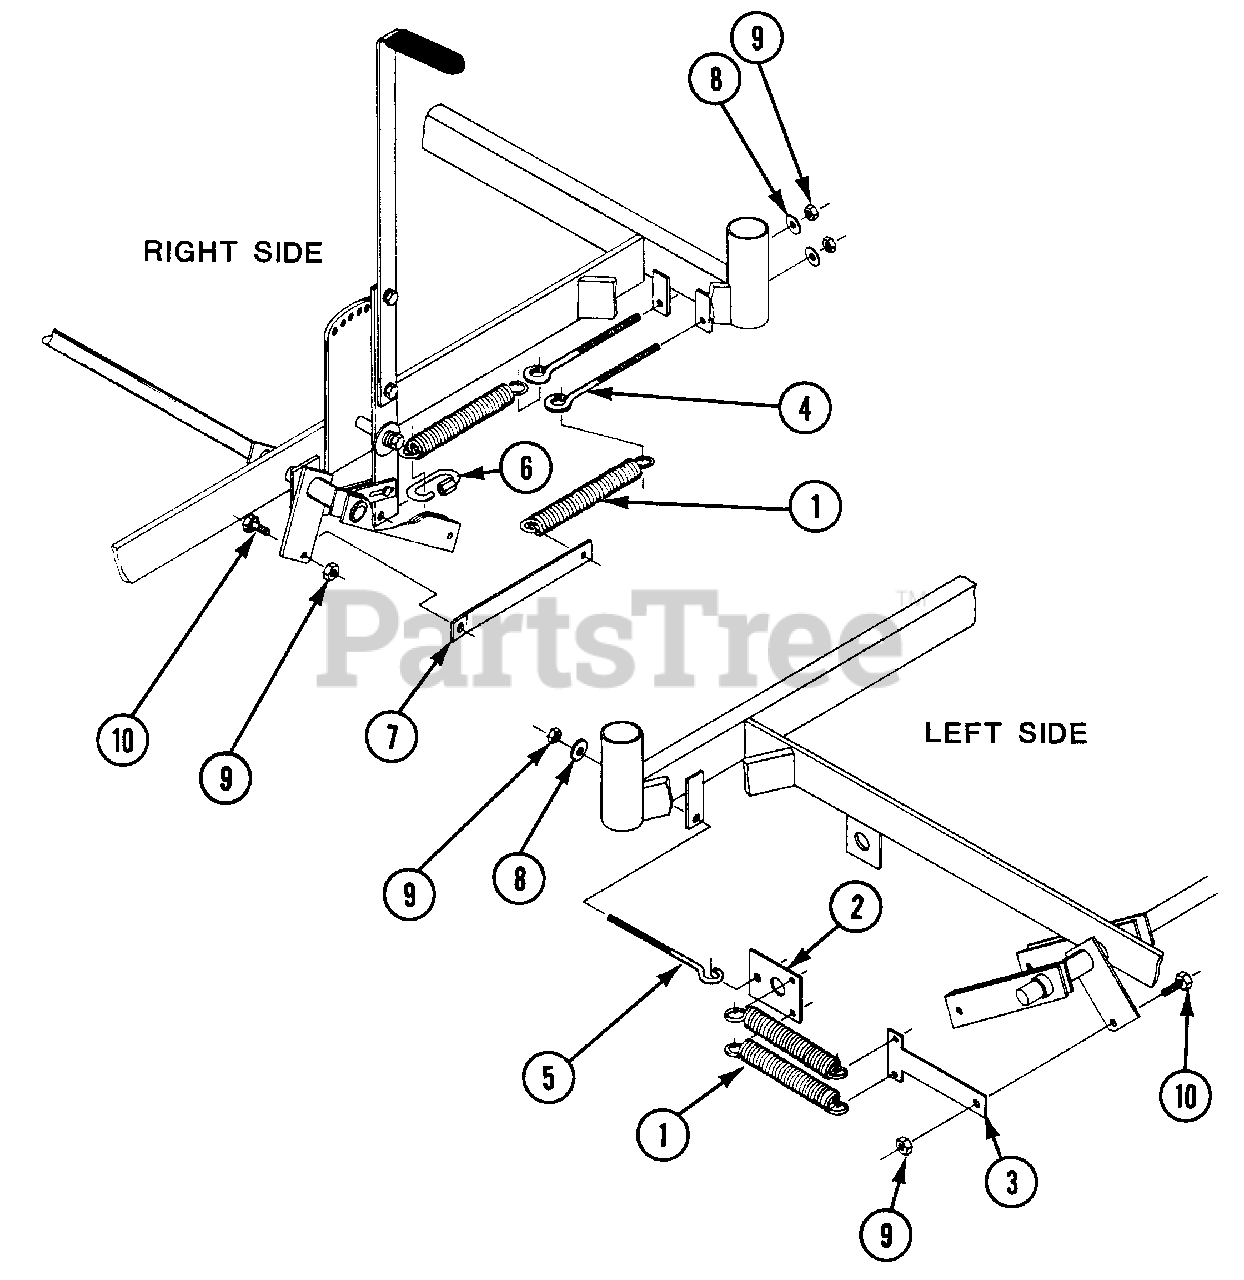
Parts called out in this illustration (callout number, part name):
1	DECK SPRINGER 1-1/2" X 8" LONG
2	SPRING EXTENSION PLATE
3	SPRING EXTENSION PLATE (T)
4	EYEBOLT 3/8-16 X 7-1/2" (FULL EYE)
5	EYEBOLT 3/8-16 X 7-1/2" (OPEN EYE)
6	CHAIN CONNECTOR
7	RIGHT SPRING EXTENSION PLATE
8	WASHER, 3/8 STD, FLAT
9	LOCKNUT, HEX, 3/8-16, W/NYLOC
10	CAPSCREW, HEX, 3/8-16 x 1-1/4
